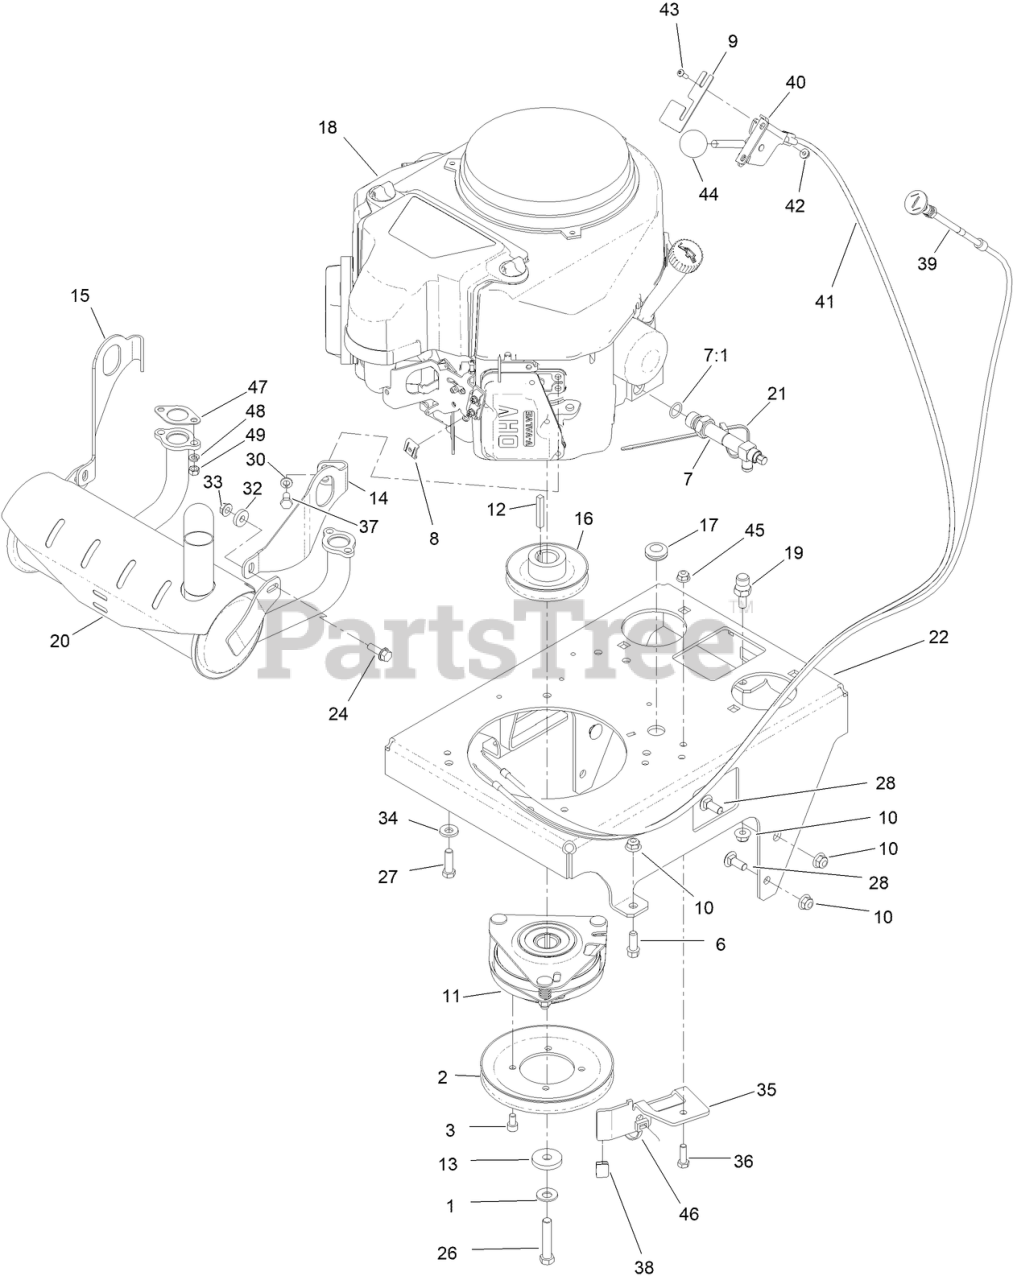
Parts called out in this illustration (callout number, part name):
1	WASHER-SPRING
2	PULLEY
3	SCREW-HSH
7	DRAIN-OIL, VALVE, KAW
7:1	O-RING
8	CLAMP-CABLE
9	PLATE-SET, THROTTLE
10	NUT-HF, NI
11	CLUTCH/BRAKE ASM
12	KEY-SQUARE
13	WASHER
14	BRACKET-MUFFLER, LH
15	BRACKET-MUFFLER, RH
16	PULLEY
17	GROMMET
19	ANCHOR-SPRING, SHORT
20	MUFFLER
21	TIE-CABLE
22	BASE-ENGINE
24	SCREW-HHF
26	SCREW-HH
27	SCREW-HH
28	BOLT-CARR
30	WASHER-LOCK
32	SPACER
33	NUT-HF
34	WASHER-BELLEVILLE
35	BRACKET-CLUTCH STOP
36	SCREW-HH
37	SCREW-HH
38	BUMPER
39	CONTROL-CHOKE, PUSH / PULL
40	LEVER-CONTROL
41	CABLE-CONTROL
42	NUT-LOCK, FLANGE
43	SCREW-HSBH
44	KNOB-BALL
45	NUT-HF, NI
46	TIE-CABLE
47	GASKET-EXHAUST
48	WASHER-LOCK
